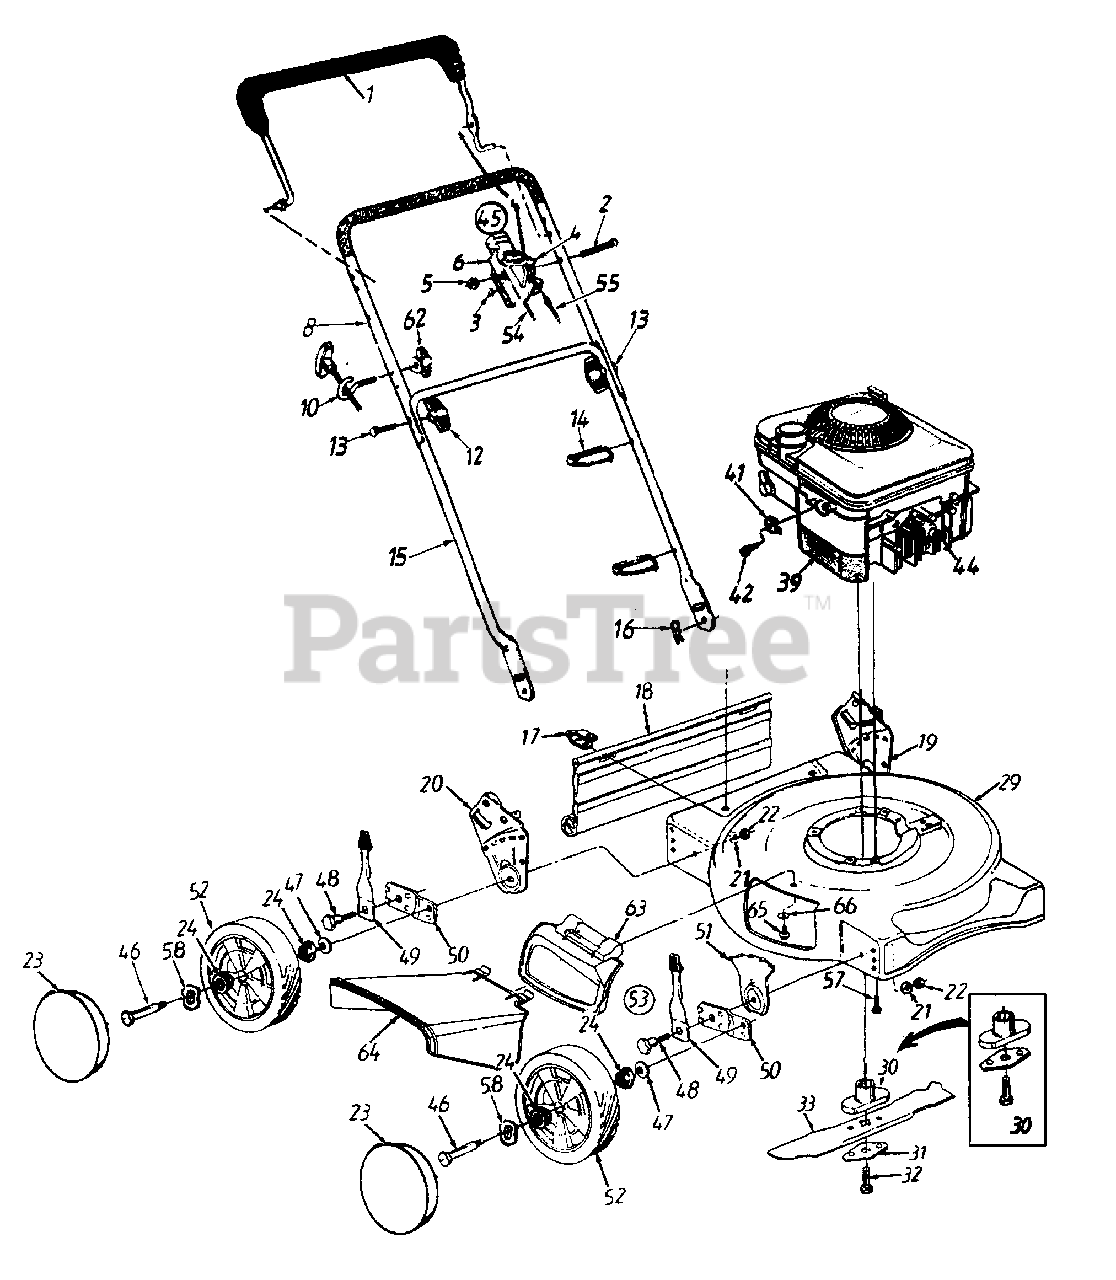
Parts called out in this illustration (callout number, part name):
1	Control Handle Ass'y.
2	Oval C-Sunk Scr.
3	Spr. Wash. .66" I.D.
4	Throttle Lever
5	Hex L-Nut 1/4-20 Thd.
6	Throttle Body
12	Hand Knob
13	Cur. Hd. Bolt 5/16-18 x 2" Lg.
14	Cable Tie
16	Hairpin Clip
17	Hinge Clip
18	Rear Flap
19	Handle Brkt. Ass'y.-L.H.
20	Handle Brkt. Ass'y.-R.H.
21	Bell-Wash. .39" I.D. x 1.38"
22	Hex Nut 3/8-16 Thd.
23	Hub Cap
24	Bearing
31	Blade Bell Support
32	Hex Bolt 7/16-20 x 1.5" Lg.
33	18" Mulching Blade
39	Engine
41	Cable Clamp
42	Hex Tap Scr. #10-32 x .62" Lg.
44	Spark Plug Boot
45	Throttle Box Comp.
46	Axle Bolt
47	Bell-Wash. .4 "I.D. x .88"
48	Shld. Bolt .5 "Dia. x .357"
49	Spring Lever Ass'y. w/Knob
51	Height Adj. Plate
52	Wheel Ass'y. Comp.
53	Height Adj. Ass'y. Comp. R.F. & L.R.
54	Throttle Cable 51" Lg.
55	Control Cable 36" Lg.
57	Hex L-Wash. Hd. Scr. 3/8-16 x 1" Lg.
58	Wave Washer
62	Handle Knob
63	Mulching Plug
64	Chute Deflector
65	Bell-Wash. 1/4" I.D.
66	Hex Wash. Hd. TT-Tap Scr. 1/4-20 x .5" Lg.
